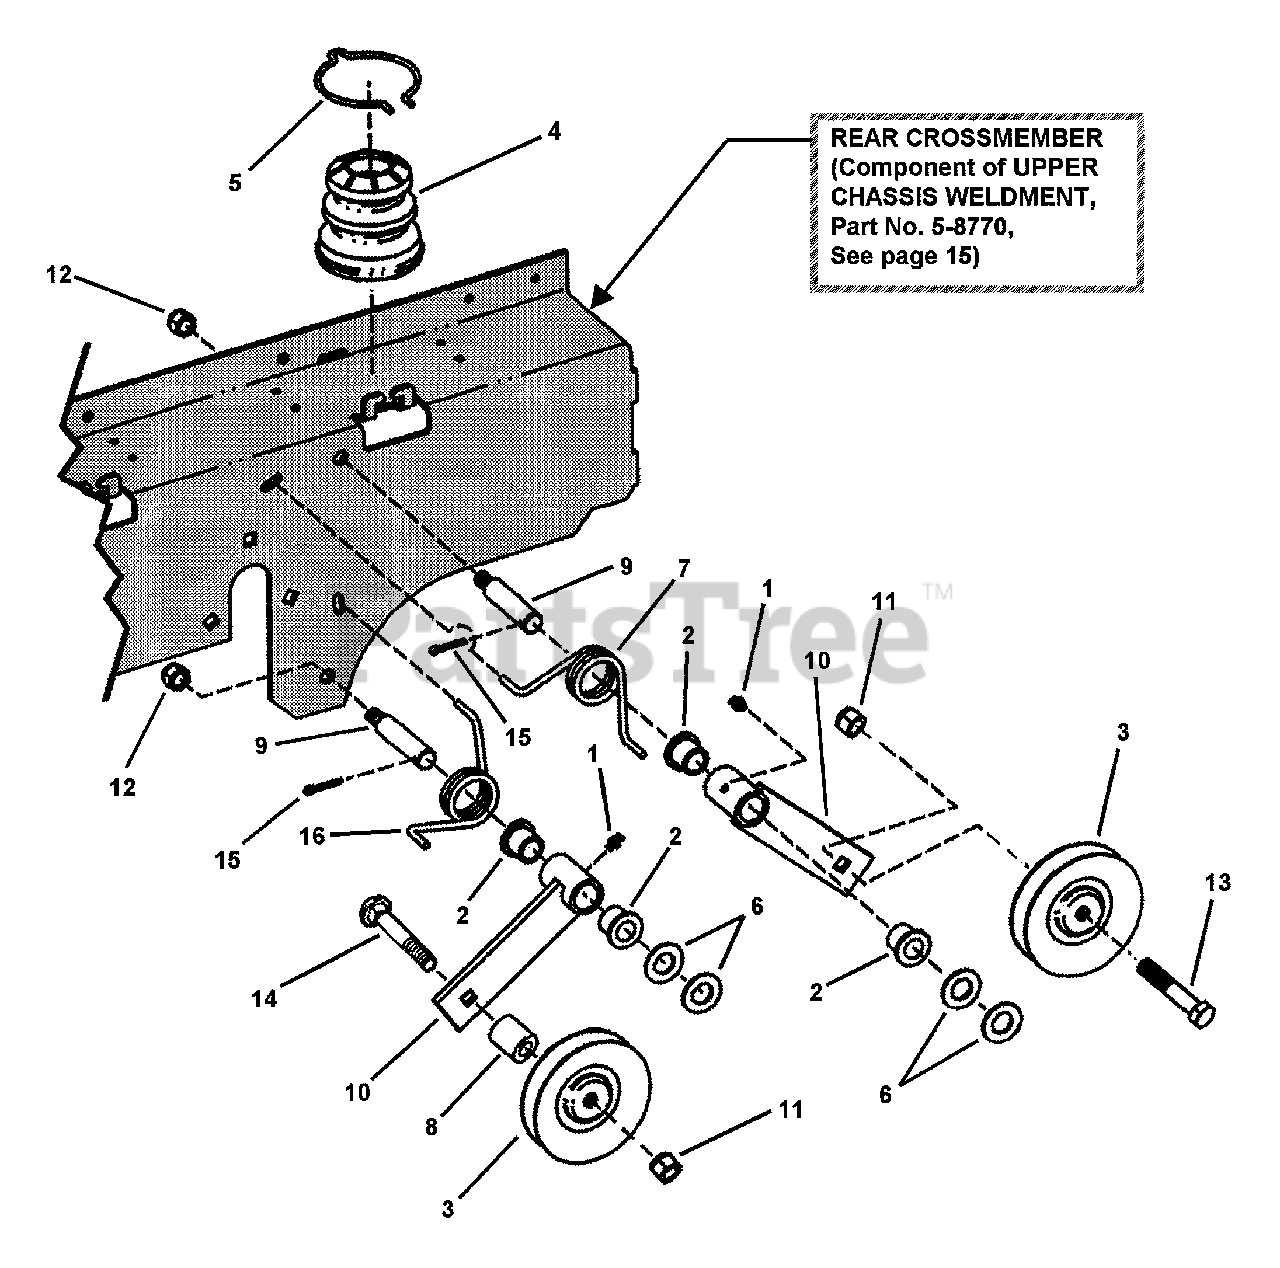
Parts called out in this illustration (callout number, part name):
1	FITTING, 3/16 Lube
2	BUSHING, 9/16 I.D., 3/4" O.D.
3	PULLEY, Idler 3.48 O.D.
4	COVER, Spring (Rubber)
5	CLIP, Seat Cushion
6	WASHER, 9/16 Flat
7	SPRING, Torsion
8	SPACER, 3/8 I.D. 5/8 O.D. x 5/8" Long
9	PIN, 3/8-24
10	IDLER ARM (Weldment)
11	NUT, 3/8-16 HEX NYLON LOCK
12	NUT, 3/8-24 Hex Nyloc
13	SCREW, 3/8-16 x 1-3/4" Hex Head Cap, Grade 5
14	BOLT, 3/8-16 x 2" Square Neck Carriage, Grade 2
15	COTTER PIN, 1/8 x 3/4"
16	SPRING, Torsion
